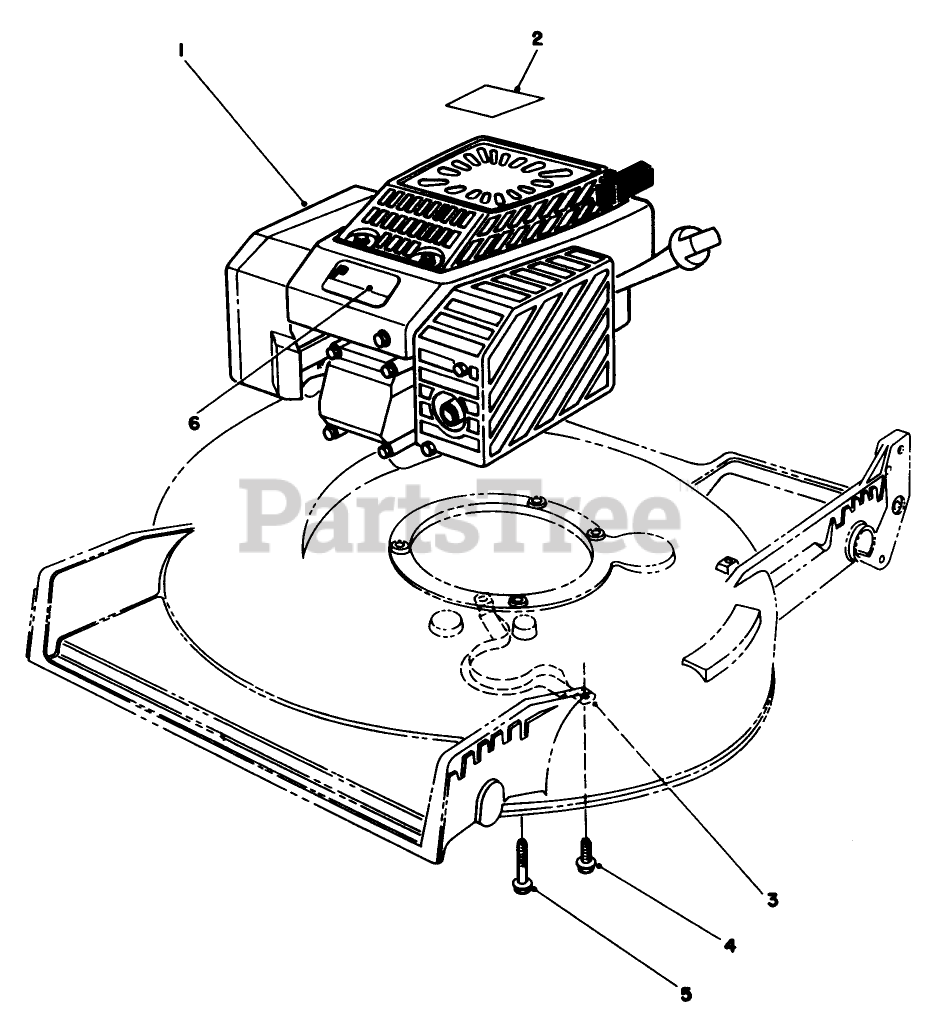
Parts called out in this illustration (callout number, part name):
1	Engine-Complete (Incl. Ref. #2, & 6)
2	DECAL - ENGINE
3	Guide-Belt
4	SCREW-HWHTF
5	SCREW-HWH
6	DECAL - PROLINE
